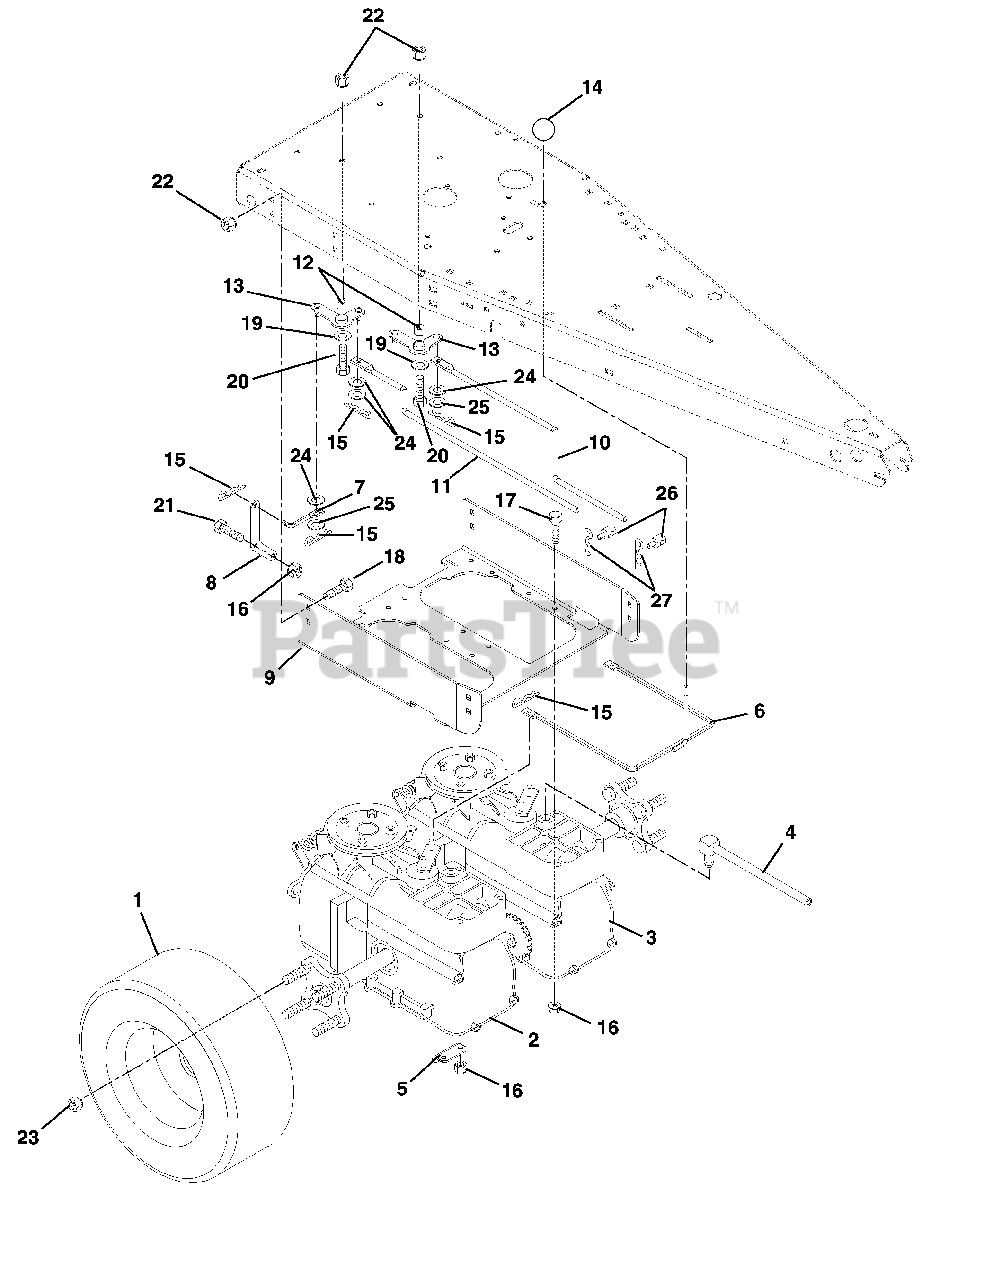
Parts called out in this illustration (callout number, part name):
1	T/WHL ASM 18X6.50-8 2 PLY
2	TRANSAXLE, HYDRO-GEAR
3	TRANSAXLE, HYDRO-GEAR
4	IZT, BREATHER ASSEMBLY
5	BRACKET-AXLE SUPPORT
6	DUMP ROD WLDM'T
7	ROD-BELL CRANK
8	BRACKET
9	CRADLE, IZT
10	ROD-STEERING LH
11	ROD-STEERING RH
12	BSHG-SLV .391X.688X.52 PM
13	WLDM'T-BELL CRANK
14	KNOB, BALL 5/16-18 X 1.5
15	PIN-HAIR, ENDRIES #25 YWZC
16	NUT-LK-TOP-FLG .31-18 BLKZC
17	@BLT-HEX .31-18X2.50 GR5 YWZC
18	BLT-RDHDSQNK .38-16X.75 G5BZ
19	@WSHR-FL-STL.38X.875X.083 YWZC
20	@BLT-HEX .38-16X1.25 GR5 YWZC
21	@BLT-HEX .31-18X.75 GR5 YWZC
22	NUT-LK-TOP-FLG .38-16 BLKZC
23	NUT-LUG .50-20 YWZC
24	WSHR-FL-STL .328X.87X.179 YWZC
25	WSHR-FL-STL .390X.75X.125 YWZC
26	TRUNNION, BRAKE .31-18 UNC
27	PIN-HAIR, ENDRIES #25 YWZC
